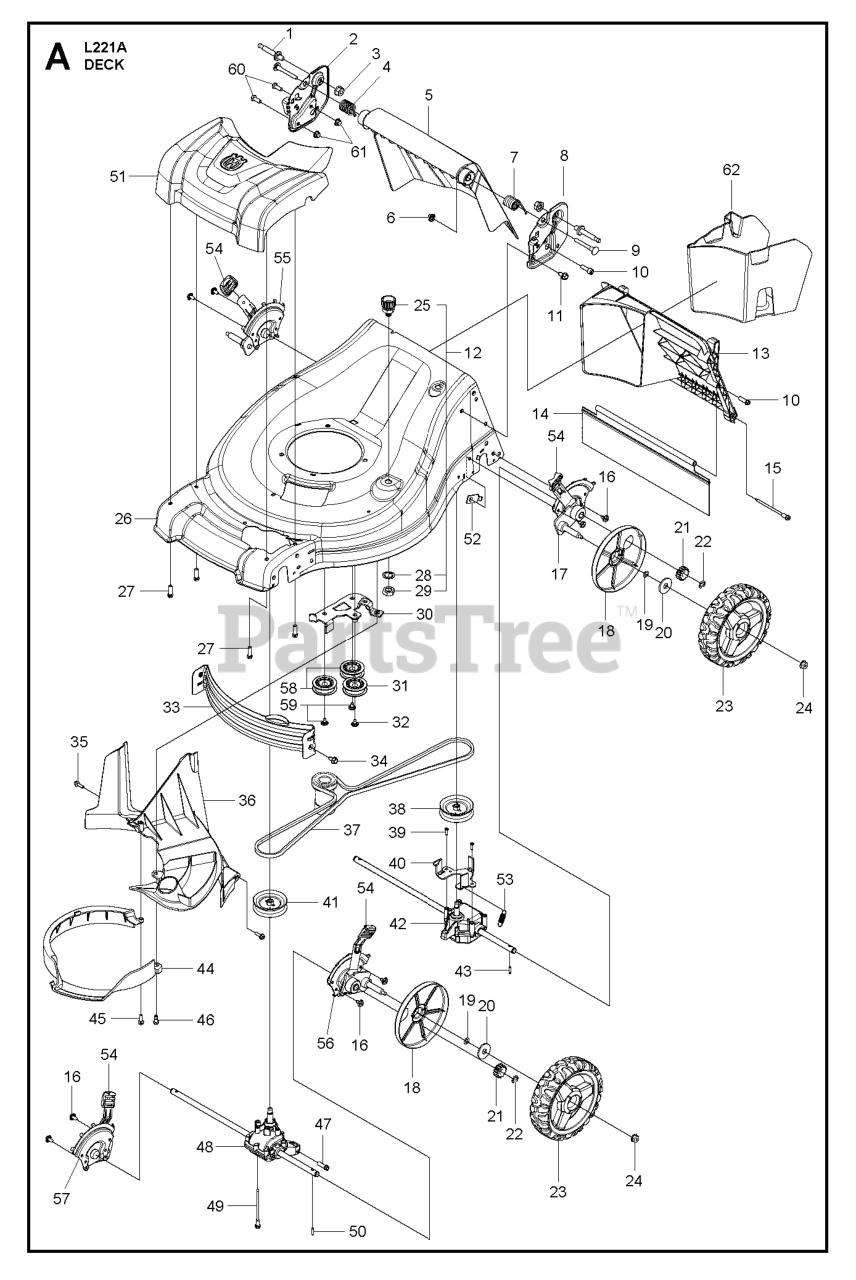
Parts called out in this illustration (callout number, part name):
1	BOLT.HAND.PIVOT.3125-18.21EFF
2	BRACKET.HANDLE.ADJ.21EF.RH.498
3	NUT.FLANGE.SERRAT.3125-18.5625
4	SPRING.RH.DOOR.21 EFF
5	DOOR REAR, 21IN EFF GRAY MS-49
6	NUT.FLANGED.3/8-16.ZINC
7	SPRING.LH.DOOR.21 EFF
8	BRACKET.HANDLE.ADJ.21EF.LH.498
9	BOLT.DOOR.PIVOT..375-16.21EFF
10	SCREW.HI-LO,5/16-14 X T-45
11	BOLT.5/16HEX.WHS.HD
12	KIT.WASH-OUT.PORT
13	INSERT.REAR.21 EFF
14	SKIRT.REAR.21 EFF
15	SCREW.HI-LO.5/16-14 X 4.10
16	SCREW
17	ADJUSTER.4PT.21EFF.RF/LR.BLK
18	COVER.DUST.WHEEL.INNER.WALK
19	O-RING..070X.487.NEOPRENE
20	WASHER FLUT
21	PINIION.14.TOOTH.RGD
22	E-RING 7/16 RE
23	WHEEL.8".AWD.3SP.EXT.DR.GREY
24	NUT.HEX.FLANGE.3/8-16.LO(3 2)
25	FITTING, HOSE, WATER WASHOUT
26	KIT.HSG.21EFF.AWD.WO.668.CE SY
27	SCREW.HI-LO. 5/16 X 1.00
28	WASHER.LOCK.INTERNAL.TOOTH
29	LOCKNUT.HEX.WITH.O-RING
30	BRACKET.ASM.IDLR.AWD.21EFF.BZP
31	PULLEY.RWD.IDLER.DBL SEAL
32	SCREW
33	BAFFLE.FRONT.21 EFF
34	BOLT.5/16HEX.WHS.HD
35	SCREW.HI-LO.13-16X.750.375XDRV
36	COVER.BELT/REAR BAFFLE.21 EFF
37	BELT.DRIVE.21EFF.AWD
38	PULLEY.DRIVE.SM.AWD/RWD
39	SCREW
40	BRACKET.TRAN.BELTKEEPER.22+RGD
41	PULLEY.DRIVE.SM.AWD/RWD
42	TRANSMISSION.AWD.REAR.21EFF
43	PAWL, DRIVE
44	RING.STRIPPER.21 EFF
45	SCREW.HI-LO.13-16X.750.375XDRV
46	BOLT SHOULDER_1/4-20_TRILOB
47	SCREW.HI-LO. 5/16 X 1.00
48	TRANSMISSION.AWD.FRONT.21EFF
49	SCREW.HI-LO.5/16-14 X 4.10
50	PAWL, DRIVE
51	COVER.DR.FULL.HUSQ.21EFF.AWD
52	STRAP.PLATE ATTACH.21 EFF.GLV
53	SPRING.RETURN.AUTO.
54	SELECTOR KNOB
55	ADJUSTER.4PT.21EFF.LF/RR.BLK
56	ADJUSTER.4PT.21EFF.LF/RR.BLK
57	ADJUSTER.4PT.21EFF.RF/LR.BLK
58	PULLEY.ASM.22+ AWD
60	BOLT.FIN.HEX.5/16-18X3/4
61	NUTNYLOK.FLRANGE.5/16-18
62	PLUG.MULCH.21 EFF
